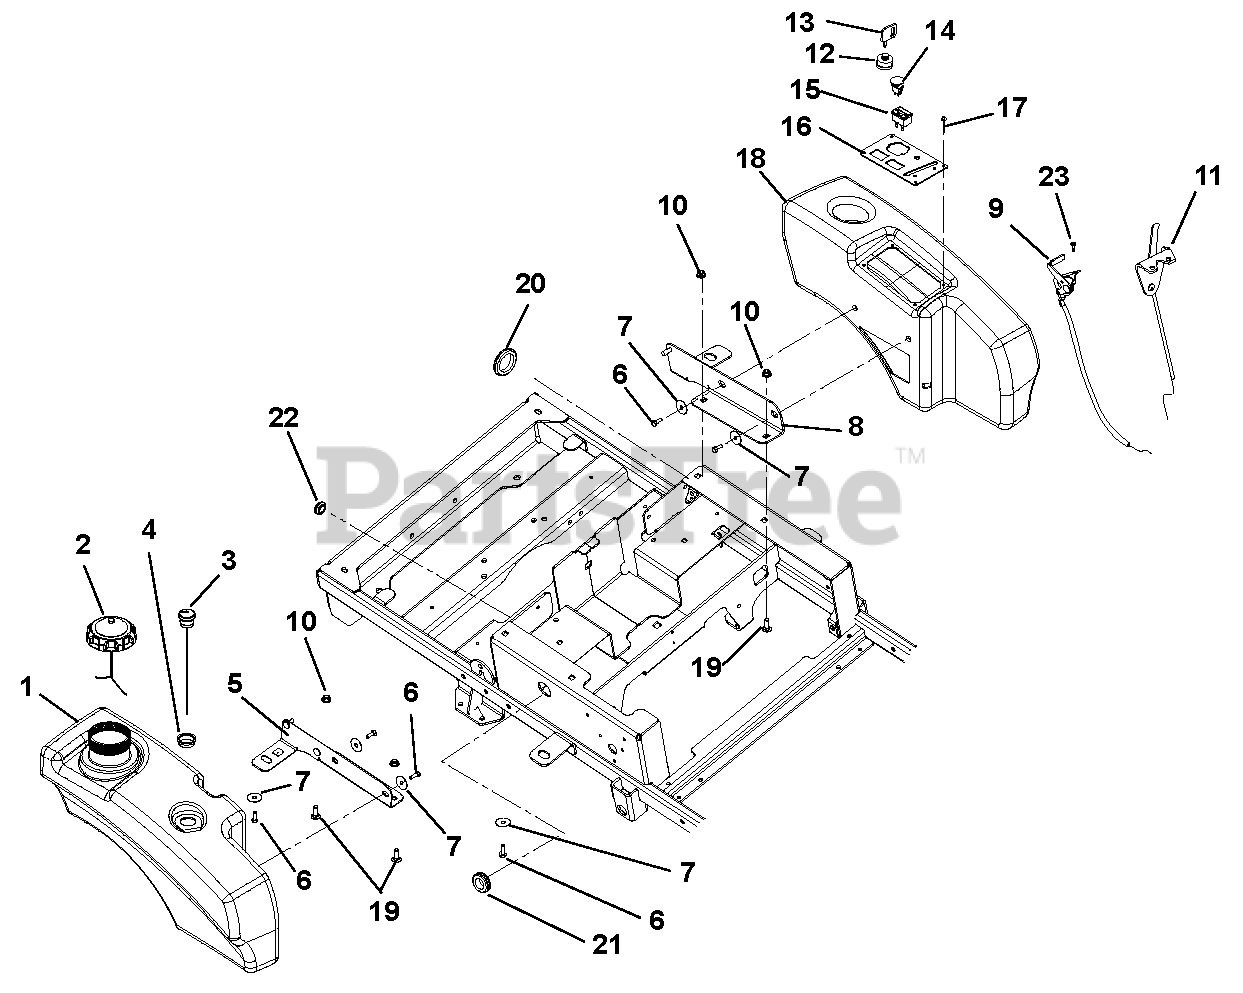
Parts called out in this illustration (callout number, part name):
1	Tank, XL
2	Fuel Cap
3	Gauge, Remote Fuel 10.0"
4	Grommet, Fuel Gage
5	Weldment, RH Tank Mount
6	Bolt, Serrated Hex Flange Washer Head .312-18 x .50
7	Washer, Flat Steel .347 x 1.254 x .048
8	Weldment, LH Fender Mount
9	Cable, Throttle
10	Nut, .38-16 Nyloc Flange
11	Cable, Choke
12	Key Switch
13	Key, w/cap
14	Switch, Clutch
15	Hour Meter, Digital
16	Panel, Control
17	Rivet, Plastic .195 Diameter
18	Fender, XL
19	Bolt, Round Head Square Neck .38-16 x 1.00 Grade 5
20	Grommet, 2.00"
21	Grommet .125 x 1.000 ID
22	Grommet, Rubber 5/8 ID/1.13 OD
23	Screw, Tapping 10-24 x .50 Hex Washer Head Thread
